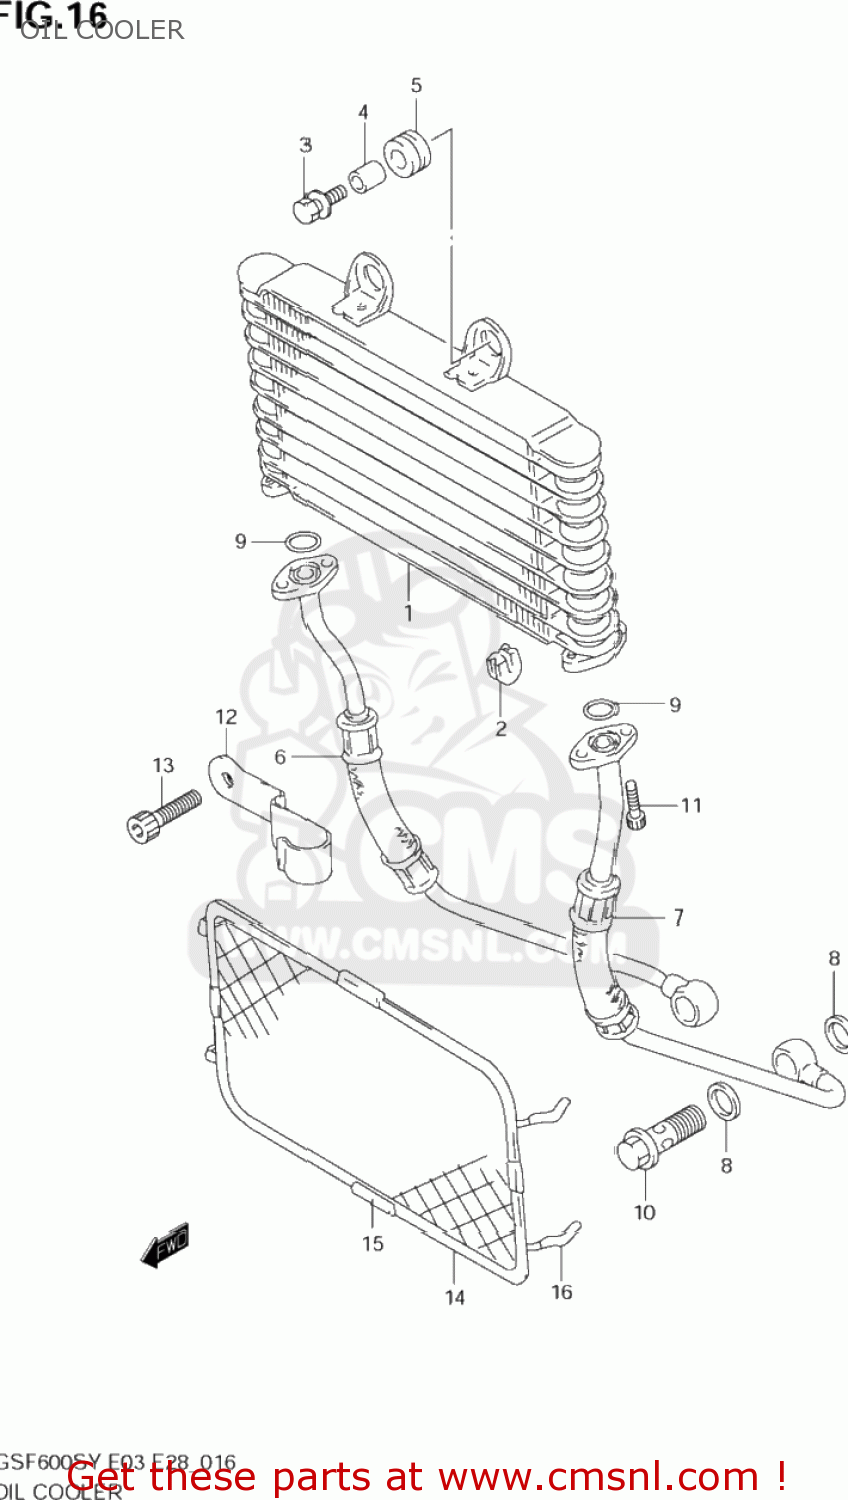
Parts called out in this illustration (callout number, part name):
1	COOLER ASSY,OIL
2	CUSHION,OIL COOLER NO.2
3	BOLT(6X20)
4	SPACER(6.5X10X10)
5	CUSHION
6	HOSE COMP,OIL COOLER,RIGHT
7	HOSE COMP,OIL
8	GASKET(16X22X2) (NAS)
9	O RING(D:2.4,ID:11.8)
10	BOLT UNION
11	BOLT,OIL FILLE
12	CLAMP,OIL HOSE
13	BOLT,STRANGER
14	GUARD,OIL COOLER
15	PROTECTOR,CTR
16	HOSE(3X5X600)
